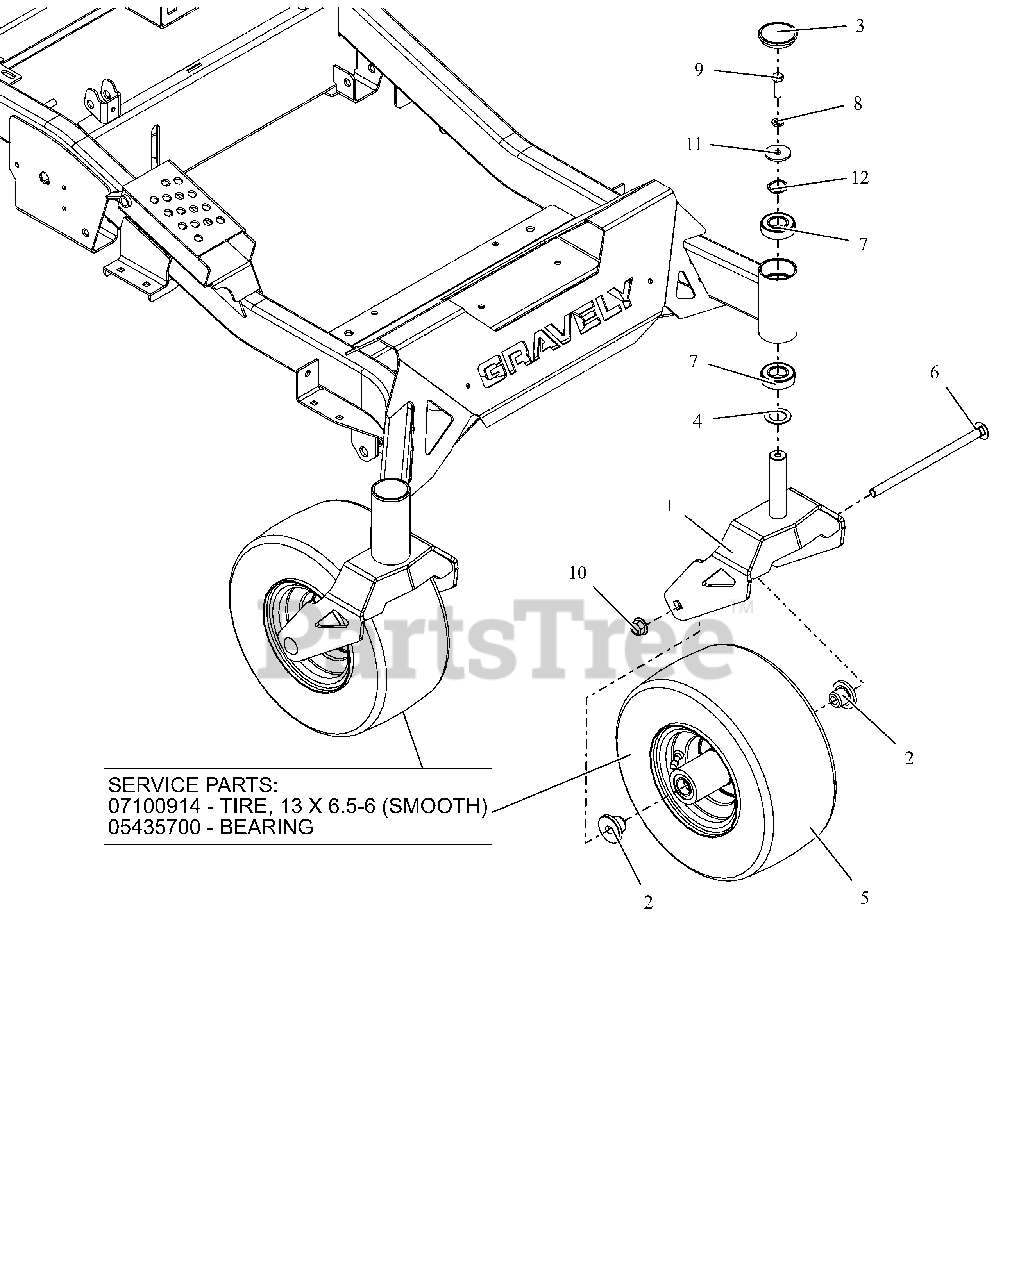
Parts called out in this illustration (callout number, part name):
1	WLDMT, HD CASTER FORK
2	SPACER, FRONT WHEEL
3	CAP, DUST
4	WSHR-HRD-THRS 1.007X1.542X.062
5	ASM, WHL/TIRE 13X6.50-6
5	TIRE, 13X6.50-6 SMOOTH
5	BRG, 25MM ID X 52MM OD X 15MM
6	BTL,RHSN .500-13 X 9 G5 ZCC
7	BRG,BALL 1.00X2.00X.563(1641)
8	WSHR, LK-HVY .375X.115 ZCC
9	BLT, HEX .38-16X1.25 G5 ZCC
10	NUT,NYL-FLG .50-13 GF ZCC
11	WSHR, FLT .380X1.50X.125 ZCC
12	WSHR-WAVE 1.0X1.25X.028 .145FH
